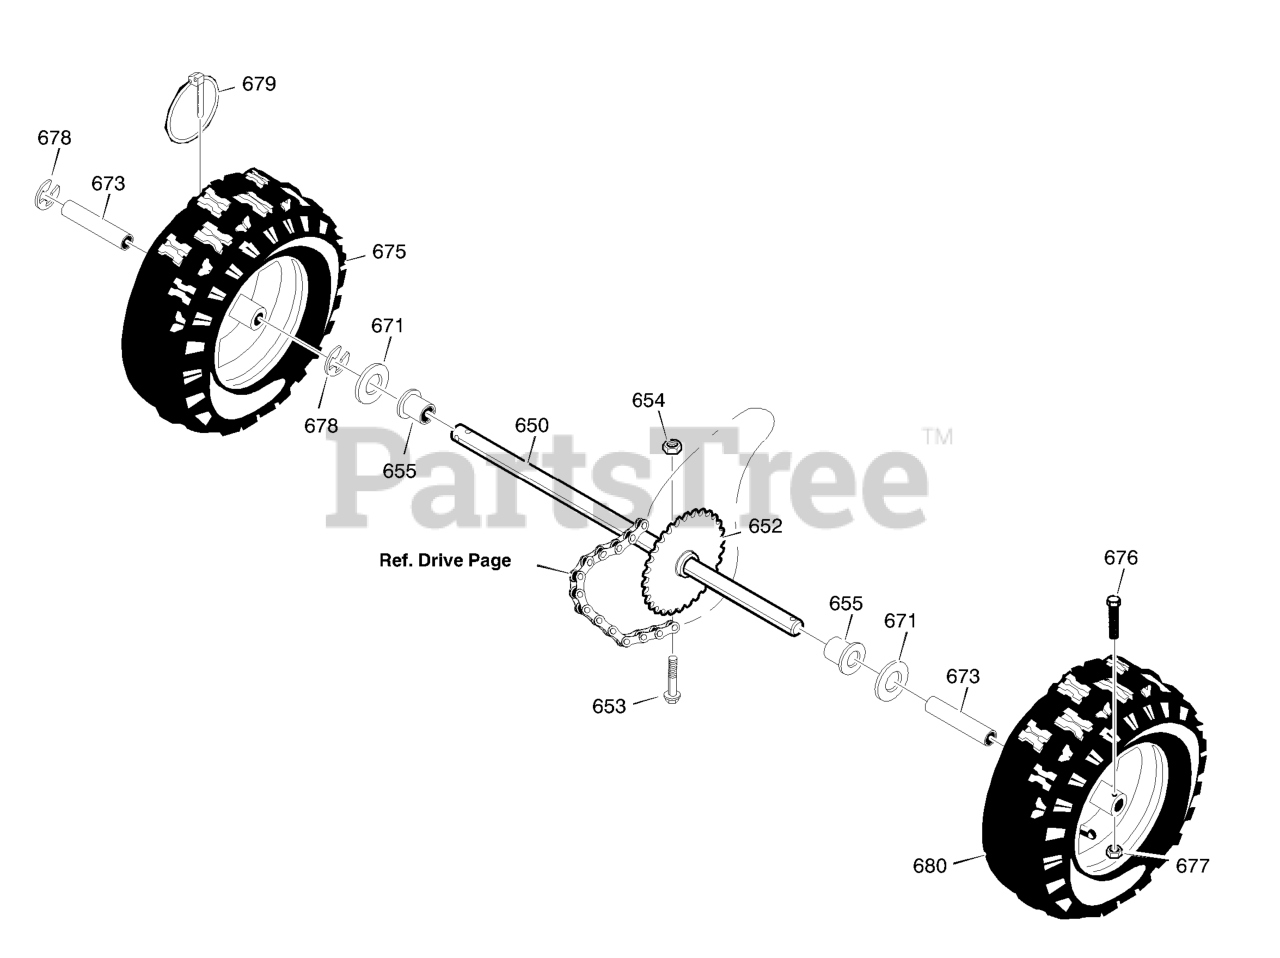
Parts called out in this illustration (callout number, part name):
650	SHAFT, AXLE
652	SPRKT & HUB
653	SCREW, 1/4-20 x 1.75
654	NUT, 1/4-20 HEX NYLOCK
655	BEARING, AXLE
671	FLATWASHER
673	BUSHING, WHEEL
675	TIRE & RIM, LEFT
676	SCREW, 1/4-20X1.75 HH
677	NUT, 1/4-20 HEX NYLOCK
678	RING, RET
679	PIN, KLIK .25 X 1.38 DIA
680	TIRE & RIM, RIGHT
